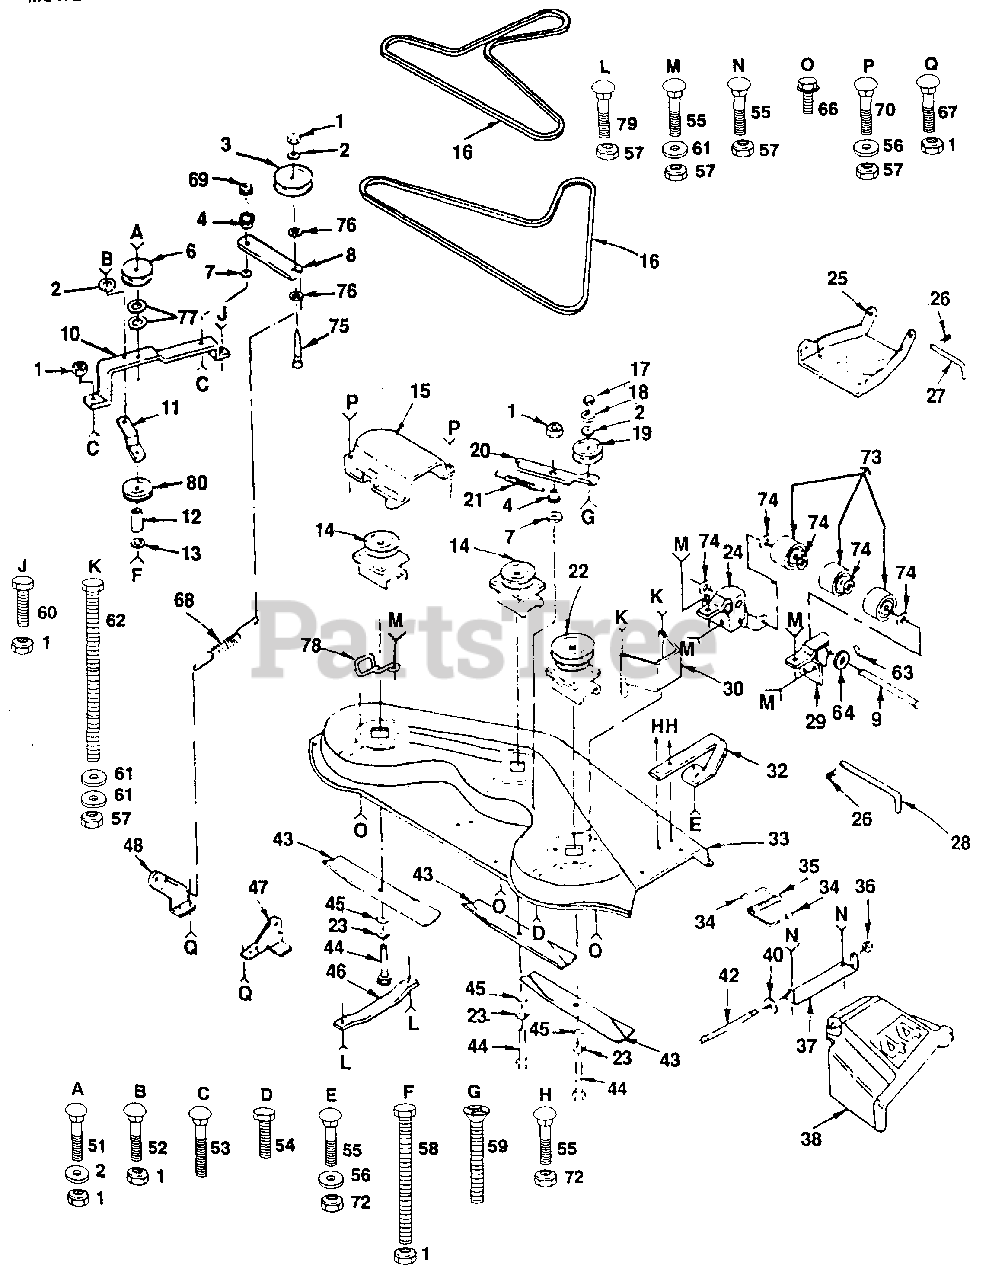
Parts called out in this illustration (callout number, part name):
1	Locknut 3/8 x 16
2	Washer 13/32 x 1 x 14 Ga. (AYP part number)
3	Pulley, Idler (AYP part number)
4	Spacer (AYP part number)
6	Pulley, Idler (AYP part number)
7	Washer, Wear (AYP part number)
8	Arm, Idler (AYP part number)
9	Pin, Pivot (AYP part number)
10	Bar, Support, Idler (AYP part number)
11	Brace, Idler, Deck (AYP part number)
12	Spacer (AYP part number)
13	Washer 13/32 x 13/16 x 16 Ga. (AYP part number)
14	Mandrel, Secondary (AYP part number)
15	Guard (AYP part number)
16	V-Belt (AYP part number)
17	Nut, Hex 3/8 x 16 (AYP part number)
18	Washer, Lock 3/8 (AYP part number)
19	Idler, Flat (AYP part number)
20	Arm, Idler, Deck (AYP part number)
21	Spring, Extension (AYP part number)
22	Mandrel, Primary (AYP part number)
23	Washer, Lock, Hvy. Helical (AYP part number)
24	Bracket, Lift, LH (AYP part number)
25	Link, Parallel (AYP part number)
26	Retainer, Spring (AYP part number)
27	Pin, Front, Hinge (AYP part number)
28	Pin, Rear, Hinge (AYP part number)
29	Bracket, Lift, RH (AYP part number)
30	Guard, Belt, RH (AYP part number)
32	Runner, RH (AYP part number)
33	Housing, Mower (AYP part number)
34	Cap, Sleeve (AYP part number)
35	Spring (AYP part number)
36	Nut, Push (AYP part number)
37	Bracket, Deflector (AYP part number)
38	Guard, Discharge (AYP part number)
40	Washer 11/32 x 5/8 x 16 Ga. (AYP part number)
42	Rod, Hinge (AYP part number)
43	Blade (AYP part number)
44	Bolt, Hex 3/8 -24 x 1 1/2 Gr.5 (AYP part number)
45	Washer 13/32 x 1 1/4 x 12 Ga. (AYP part number)
46	Runner, LH (AYP part number)
47	Bracket, Suspension, Rear, RH (AYP part number)
48	Bracket, Suspension, Rear, LH (AYP part number)
51	Bolt, Carriage 3/8-16 x 1-3/4 (AYP part number)
52	Bolt, Carriage 3/8-16 x 1 (AYP part number)
53	Bolt, Carriage 3/8-16 x 1 1/2 (AYP part number)
54	Bolt, Hex 3/8-16 x 1-1/4 (AYP part number)
55	Bolt, Carriage 5/16-18 x 3/4
56	Washer 11/32 x 11/16 x 16 Ga. (AYP part number)
57	Locknut 5/16-18
58	Bolt, Hex 3/8-16 x 3 (AYP part number)
59	Screw, Flat Head 3/8-16 x 2 (AYP part number)
60	Bolt, Fin. Hex 3/8-16 X 1 (AYP part number)
61	Washer 11/32 x 3/4 x 16 Ga. (AYP part number)
62	Bolt, Hex 5/16-18 x 5 (AYP part number)
63	Pin, Cotter (AYP part number)
64	Washer, 15/32 X 1X 16 Ga. (AYP part number)
66	Screw, Hex Washer Thread Rolling 3/8-16 x 3/4 (AYP part number)
67	Bolt, Carriage 3/8-16 x 3/4 (AYP part number)
68	Spring, Extension (AYP part number)
69	Nut.Centerlock 3/8-16 (AYP part number)
70	Bolt, Carriage 5/16-18 x 3/4 (AYP part number)
72	Locknut 5/16-18 (AYP part number)
73	Roller, Nose (AYP part number)
74	Washer 15/32 x 1 x 10 Ga. (AYP part number)
75	Bolt, Carriage 3/8-16 x 2-1/2 (AYP part number)
76	Washer 13/32 x 3/4 x 10 Ga. (AYP part number)
77	Washer 13/32 x 7/8 x 10 Ga. (AYP part number)
78	Keeper, L.H. Mandrel (AYP part number)
79	Bolt, Carriage 5/16-18 x 5/8 (AYP part number)
80	Idler, Pulley (AYP part number)
